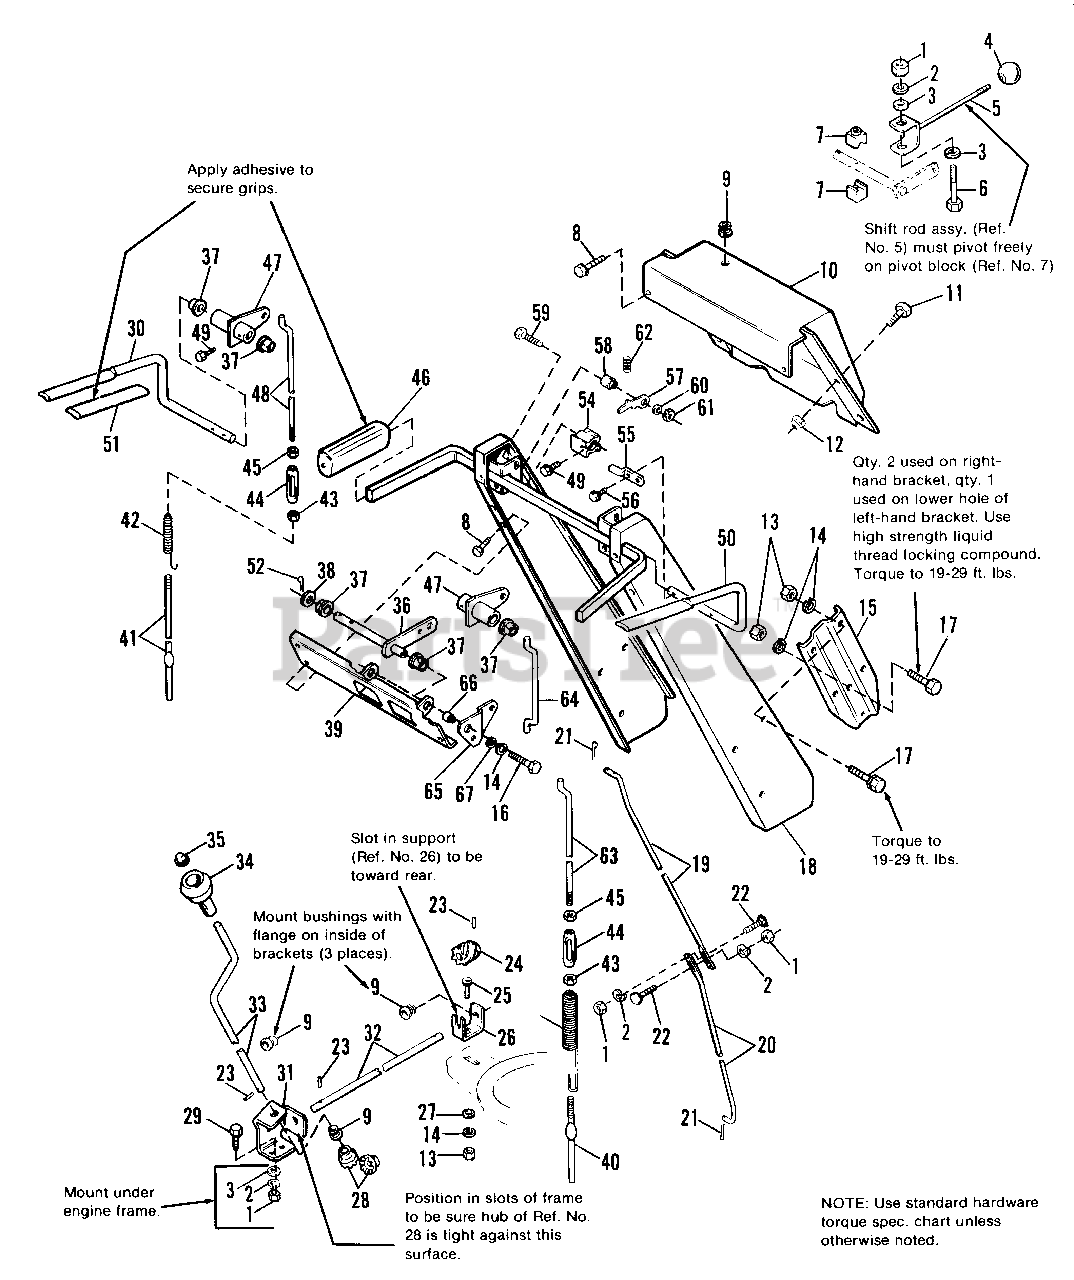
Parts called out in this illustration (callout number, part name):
1	NUT, Hex, 1/4-20
2	LOCKWASHER, 1/4
3	WASHER, Flat, 1/4
5	SHIFT ROD ASSY.
6	CAPSCREW, Hex Hd., 1/4-20 x 2-1/4
7	BLOCK, Pivot
8	SCREW, Taptite, 1/4-20 x 1/2
9	BUSHING, Plastic
10	DASH, Handle
11	CAPSCREW, Washer Hd., 1/4-20 x 3/4
12	NUT, Nylon Lock, 1/4-20
13	NUT, Hex, 5/16-18
14	LOCKWASHER, 5/16
15	BRACKET, Handle Mtg.
16	CAPSCREW, Hex Hd., 5/16-18 x 1-3/4
17	CAPSCREW, Whizlock, 5/16-18 x 3/4
18	HANDLE ASSY.
19	ROD, Shift-Upper
20	ROD, Shift-Lower
21	PIN Cotter
22	BOLT, Carriage, 1/4-20 x 3/4
23	PIN, Roll, 1/8 x 3/4
24	WORM, Chute
25	BOLT, Carriage, 5/16-18 x 3/4
26	SUPPORT, Worm
27	WASHER, Flat, 5/16
28	GEAR, Universal
29	CAPSCREW, Hex Hd., 1/4-20 x 3/4
30	HANDLE, Clutch, L.H.
31	SUPPORT, Universal Gear
32	ROD, Chute Worm
33	ROD, Chute Control
34	KNOB, Spinner
35	PALNUT
36	PIVOT ROD ASSY.
37	BUSHING, Plastic
38	WASHER
39	BRACKET, Shift Control
40	ROD, Clutch-Lower, Auger
41	ROD, Clutch-Lower, Traction
43	NUT, Hex, #10-24, R.H.
45	NUT, Hex, #10-24, L.H.
46	GRIP, Handle Bar
47	CLUTCH LEVER ASSY.
48	ROD, Clutch-Upper
49	SCREW, Taptite, #10-24 x 1
50	HANDLE, Clutch R.H.
51	GRIP, Clutch
52	PIN, Cotter, 1/8 x 1
54	GUIDE, Control
55	ROD, Control
56	SCREW, Taptite, #10-32 x 1.00
57	LATCH, Control
58	SPACER, Special
59	CAPSCREW, Hex Hd., 5/16-18 x 1-1/2
60	WASHER, Plain
61	NUT, Hex Lock, 5/16-18
62	SPRING
63	ROD, Upper Clutch, Auger
64	ROD, Clutch
65	LEVER, Clutch
67	WASHER, Plain, 5/16 x 1
